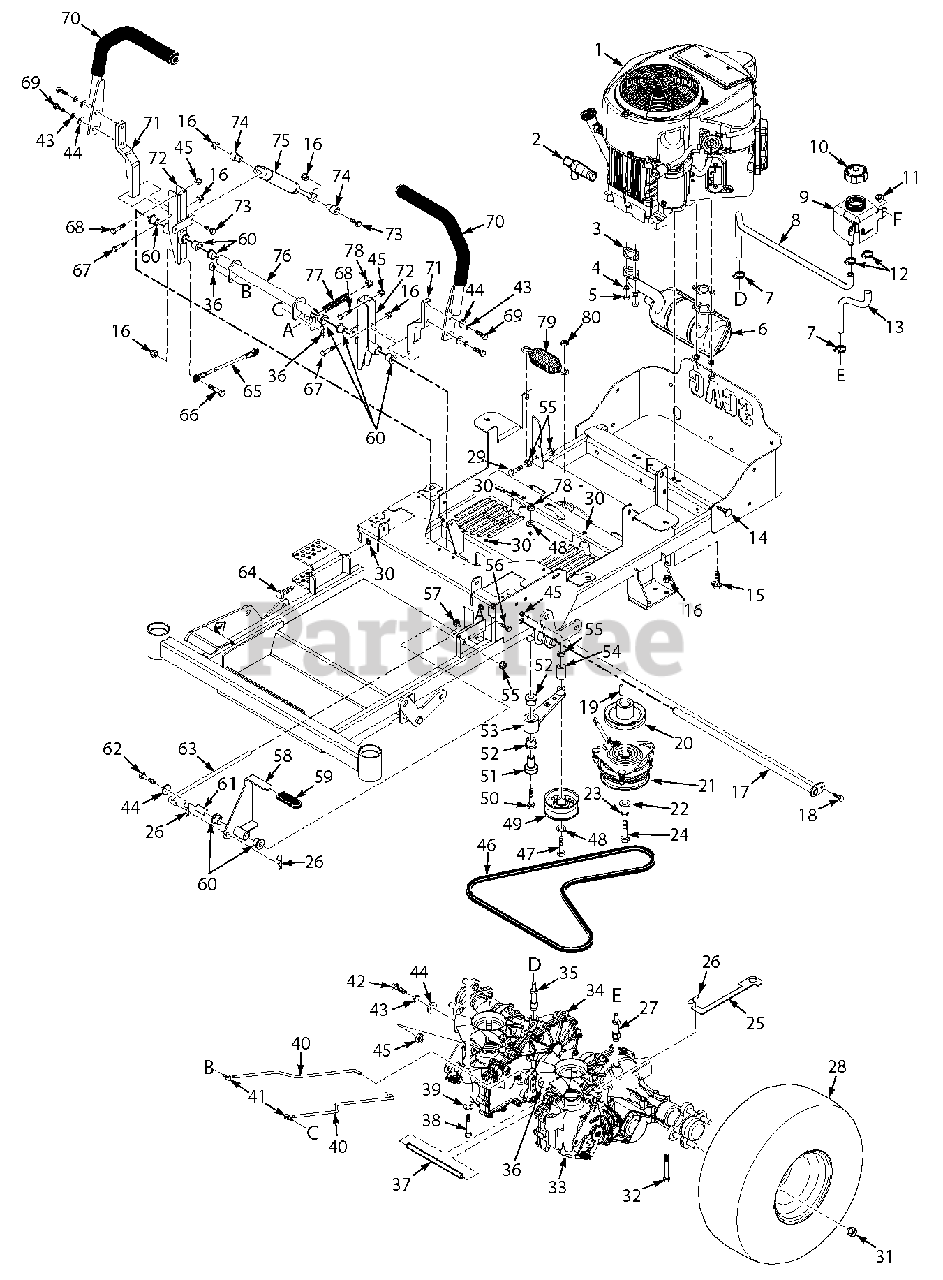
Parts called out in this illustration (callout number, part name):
1	Engine, Kawasaki - FR600V
2	Oil Drain, Kawasaki
3	Gasket, Exhaust
4	Nut, M8 x 1.25 Hex Special
5	Lockwasher, M8 Metric Spring
6	Muffler, Kawasaki FR600V
7	Clamp, .69 Max. Dia.
8	Hose, RH Transaxle
9	Reservoir Assembly
11	Nut, 1/4-20 Flange Elastic Stop
12	Clamp, .87 Max. Dia.
13	Hose, LH Transmission
14	Bolt, Carriage 1/4-20 x 3/4"
15	Screw, Hex Head 3/8-16 x 1-1/4" Self Tap
16	Nut, 5/16-18 Elastic Stop
17	Shaft Weldment, Control Arm
18	Bolt, Hex Head 1/4-20 x 5/8"
19	Key, 1/4 x 1/4 x 1-1/4"
20	Pulley, 4-1/2" - 1" Bore
21	Clutch, GT1- 1" Bore
22	Flatwasher, 7/16-.496 x 1.75 x .25
23	Lockwasher, 7/16"
24	Bolt, 7/16-20 x 3" w/Patch
25	Lever, Dump Valve
26	Hair Pin Cotter, .080 x 1.19
27	Fitting, O-Ring x 3/8" Hose
28	Wheel Assembly, 20 x 8.0-10
28	Rim W/Valve Stem 10 x 5.0
28	Tire, 20 x 8.0-10
29	Bolt, Hex Head 3/8-16 x 1-1/2"
30	Threaded insert, Hex Head (Pressed)
31	Wheel Nut, 1/2-20 x 13/16
32	Bolt, Hex Head 3/8-16 x 1-1/2"
33	Transaxle, LH- ZT-2800
34	Transaxle, RH- ZT2800
35	Fitting, O-Ring 9/16 Hose
36	Pin, Rue Cotter - 3/8"
37	Spacer, Axle
38	Bolt, Hex Head 5/16-18 x 2-1/4
39	Flatwasher, 5/16-.375 x .875 x .083
40	Rod, Brake
41	Joint, Swivel
42	Bolt, Hex Head 1/4-20 x 1-1/2
43	Lockwasher, 3/8"
44	Flatwasher, 3/8-.391 x .938 x .105
45	Nut, 1/4-20 Elastic Stop Nut
46	Belt, Transmission SZL-36
47	Bolt, Hex Head 3/8-16 x 3-3/4"
48	Flatwasher, 3/8-.391 x .938 x .105
49	Pulley, 3-1/2" Idler
50	Bolt, Hex Head 3/8-16 x 3"
51	Shaft, Pivot Idler Arm
52	Bearing, .750 I.D. Plastic
53	Idler Arm Assembly
54	Spacer, Pump Idler
55	Nut, 3/8-16 Serrated Flange
56	Bolt, Hex Head 5/16-18
57	Nut, 1/4-20 Serrated Flange
58	Brake Lever Assembly, SZL-36
59	Grip, Brake Handle
60	Bearing
61	Pivot, Brake Lever
62	Bolt, Hex Head 3/8-16 x 2-1/2"
63	Rod, Upper Brake Linkage
64	Bolt, Hex Head 3/8-16 x 3.0
65	Linkage Assembly, Steering
66	Bolt, Hex Head 5/16-18 x 1-1/4
67	Bolt, Hex Head 5/16-18 x 1-3/4"
68	Bolt, Hex Head 1/4-20 x 1-3/4"
69	Bolt, Hex Head 3/8-16 x 1-1/4"
70	Handlebar W/ Grip, SZL-36
71	Lever, Control Arm
72	Control Arm Weldment, SZL-36
73	Bolt, Hex Head 5/16-18 x 1-1/2"
74	Spacer, Pump Dampener
75	Dampener
76	Bellcrank Assembly, Brake
77	Spring, Brake
78	Nut, 3/8-16 x 16 Elastic Stop
79	Spring, Transmission Drive
80	Nut, 3/8-16 Center Lock
